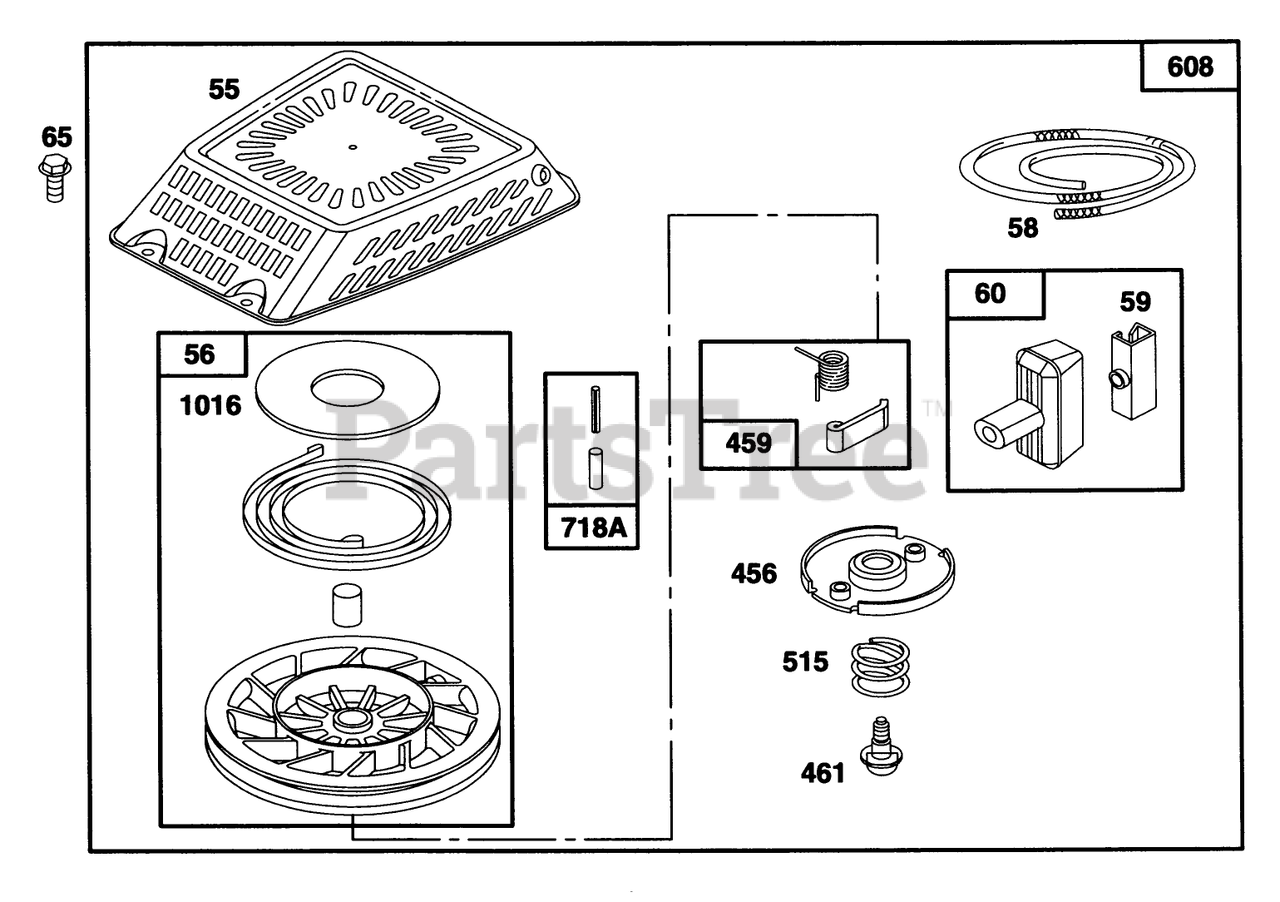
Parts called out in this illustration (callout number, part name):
59	INSERT-HANDLE, REWIND
456	RETAINER - SPRING
515	SPRING - RETAINER
